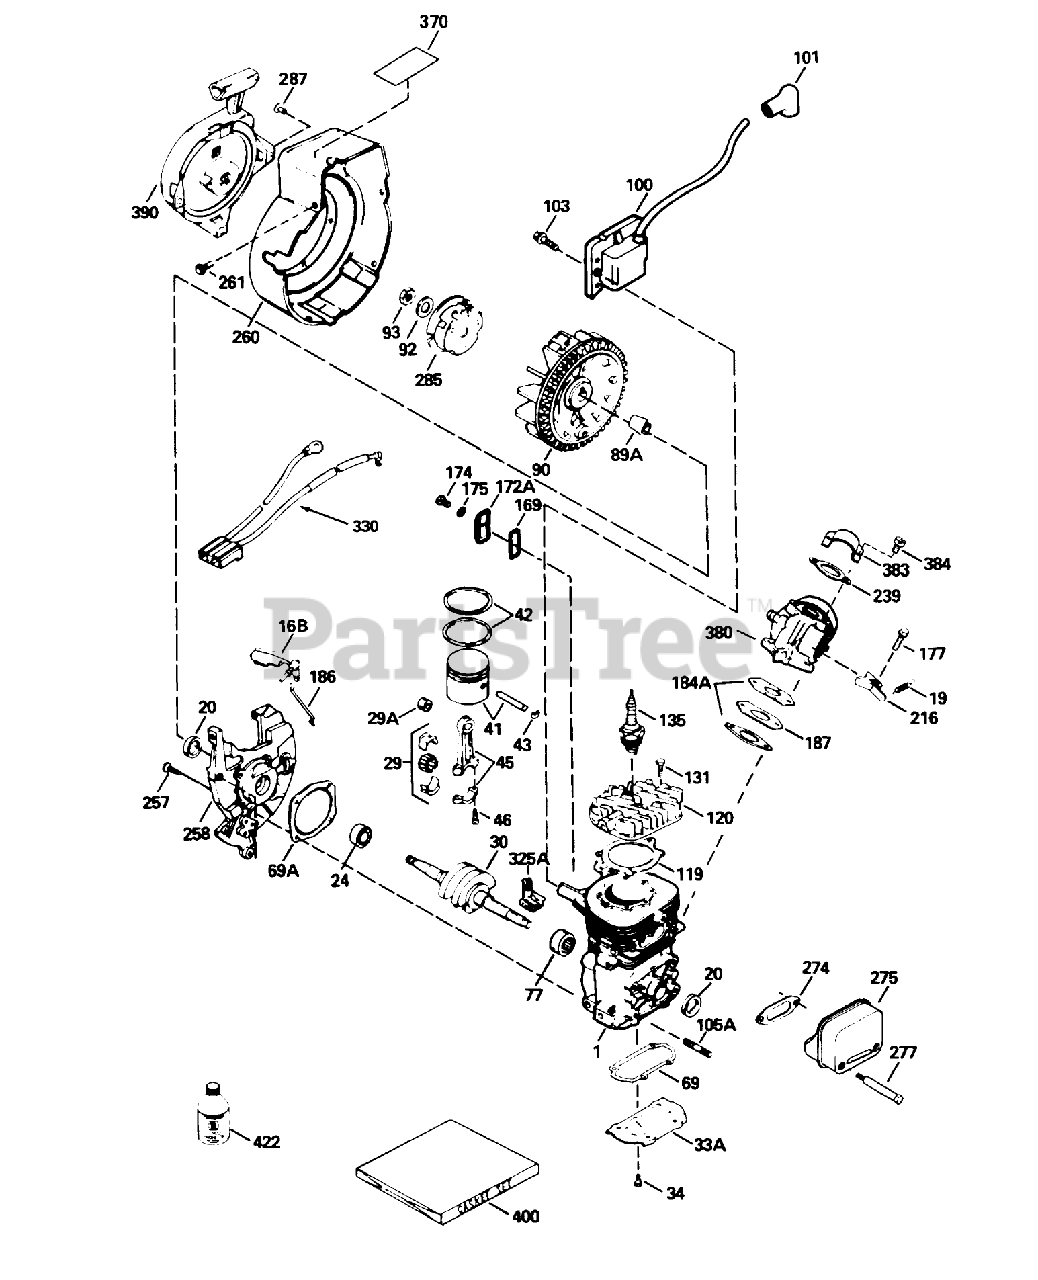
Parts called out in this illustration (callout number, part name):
1	Block Ass-y-Cylinder (Order short block if replacement is required)
16B	Vane-Air
19	Spring-Extention
20	Seal-Oil
24	Bearing-Ball
29	Needle Bearing and Liner Set (37 Needles)
29A	Bearing-Cartridge
30	Crankshaft
33A	Plate-Cover
34	Screw (T-25, 10-24 x 1/2)
41	Piston (Incl. Ref. #43)
42	Ring Set
43	Ring-Retaning
45	Rod Assy.-Connecting (Incl. Ref. #3, 3A 3B)
46	Bolt-Rod, Connecting
69	Gasket-Plate, Cover
69A	Gasket-Cover, Cylinder
77	Bearing-Cartridge
89A	Blade (20 inch)
90	CARB BODY S
92	Washer-Belleville
93	Nut-Flywheel
100	Solid State
101	Cover-Spark Plug
103	Screw
119	Gasket-Head, Cylinder
120	Head-Cylinder
131	Screw (T-30, 1/4-20 x 3/4)
135	Spark Plug-Resistor (R C J 8Y)
169	Cover-Compression, Release
172A	Comp. Release Cover
174	Screw (T-25, 10-24 x 1/2)
175	Washer
177	Screw (5/32 Allen, 1/4-20 x 1)
184A	Gasket-Carburetor
186	Link-Governor
187	Spacer
216	Lever-Adjusting, Rpm
239	2060A77 WIZARD ROTA
257	Screw (T-30, 1/4-20 x 5/8)
258	Base Ass-y-Blower Housing (Incl Ref. #20)
260	Housing-Blower
261	Screw (1/4-20 x 1/2)
274	Gasket-Exhaust
275	Muffler (Incl. Ref. #274 277)
277	Screw (1/4-20 x 2-3/4)
285	Cup-Starter
287	Rivet-Pop
325A	Clip-Wire
330	Harness-Wire
380	Carburetor (Incl. Ref. #184A)
383	Baffle-Carburetor
384	Screw
390	Starter-Rewind
400	Gasket Set
422	2-Cycle Oil (8oz)
